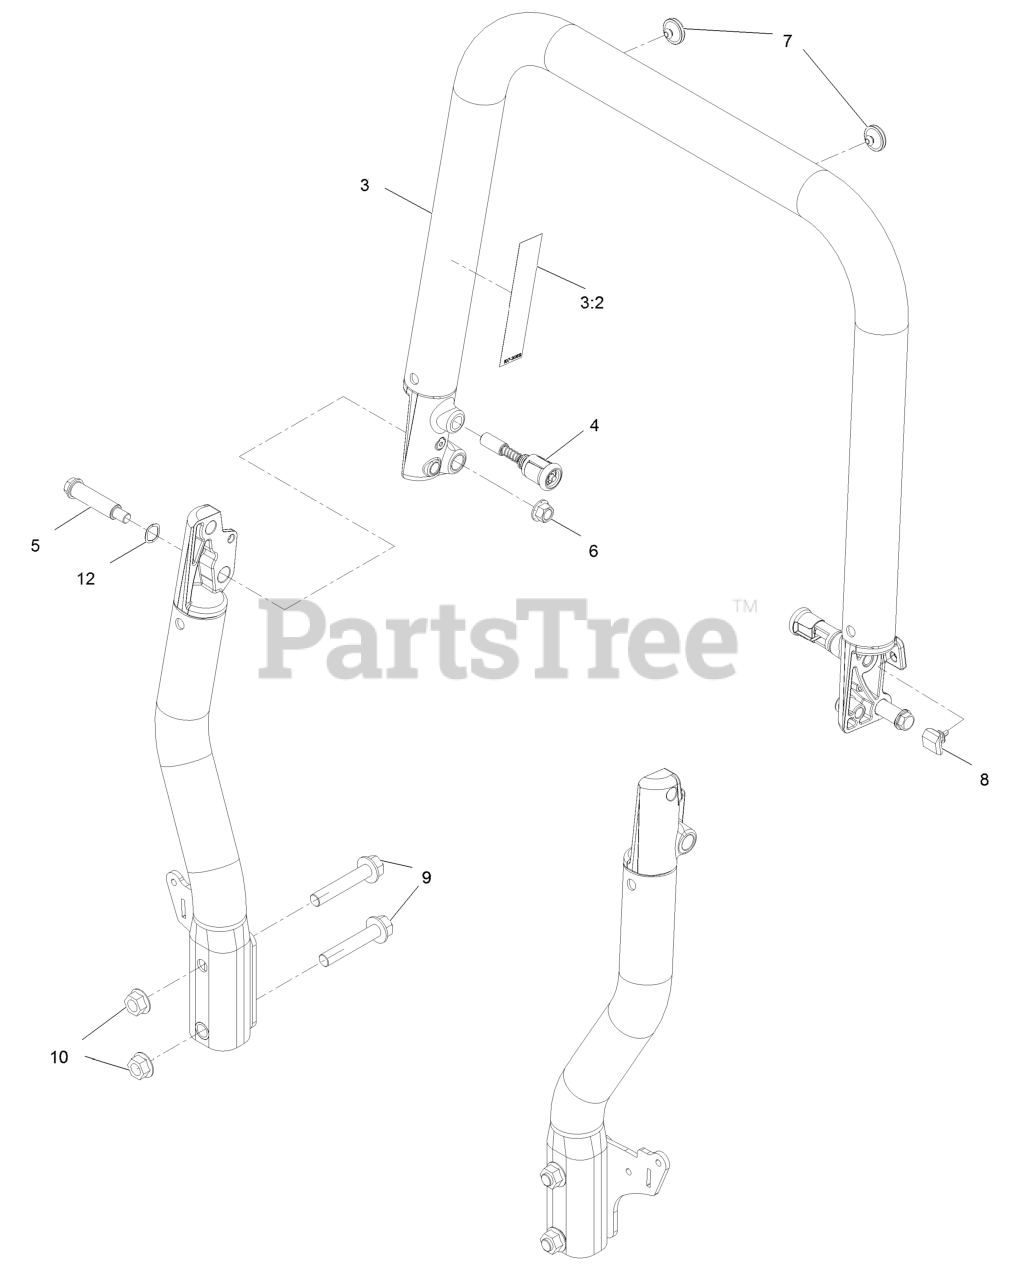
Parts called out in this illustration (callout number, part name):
3	Top Tube ASM
3:2	Decal-Warning
4	Pin-Spring
5	Bolt-Shoulder
6	Nut-Lock
7	Bumper, ROPS
8	Bumper-ROPS
9	Screw-HHF
10	Nut-Flange
12	Washer-Wave
